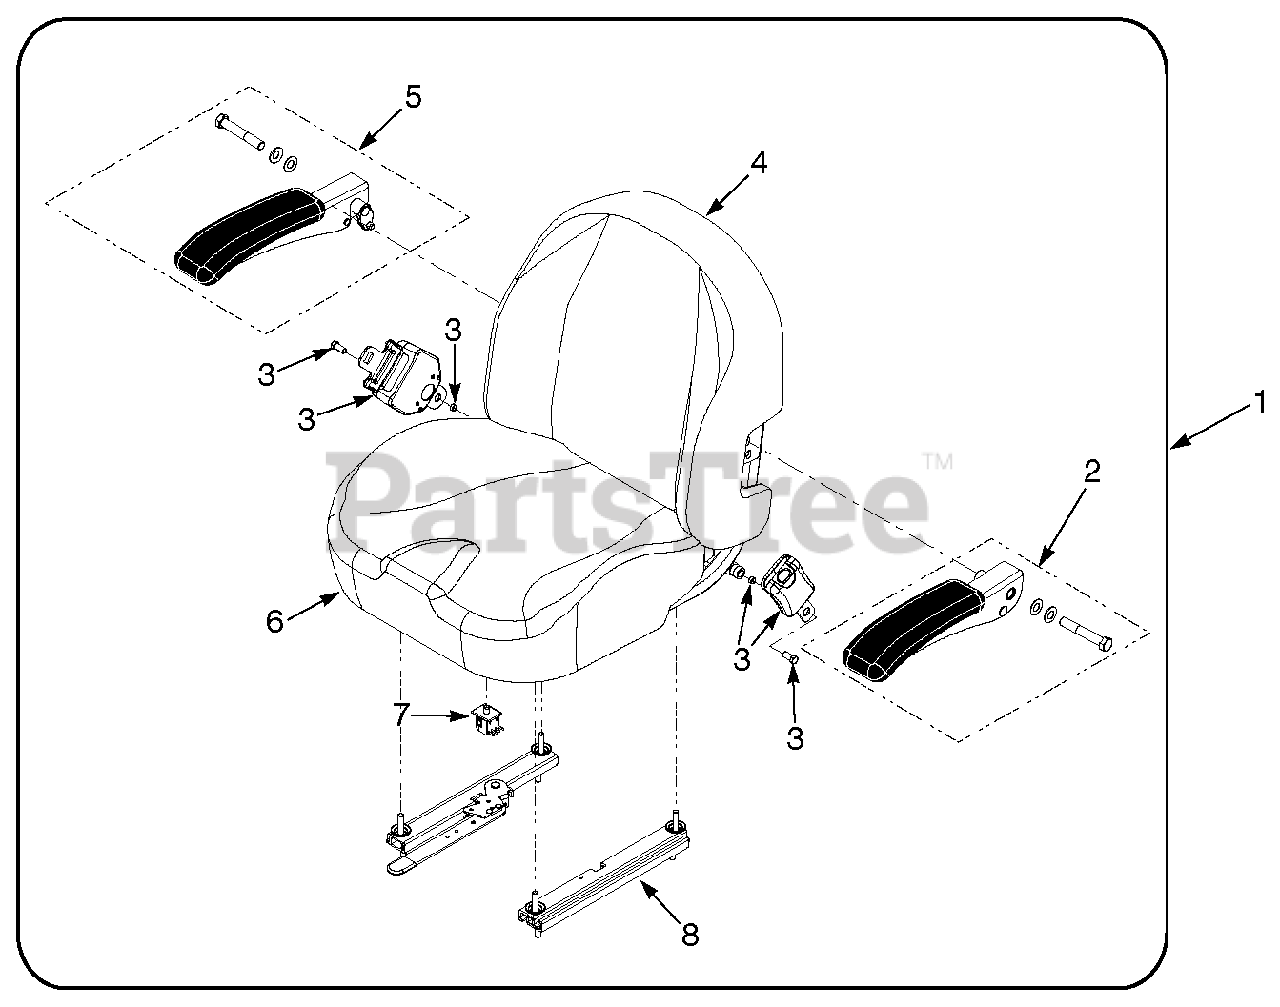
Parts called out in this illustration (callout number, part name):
1	Seat Assembly
2	Armrest Kit, LH
3	Seatbelt Kit
4	Back Cover
5	Armrest Kit, RH
6	Cushion Cover
7	Switch
8	Track Set
